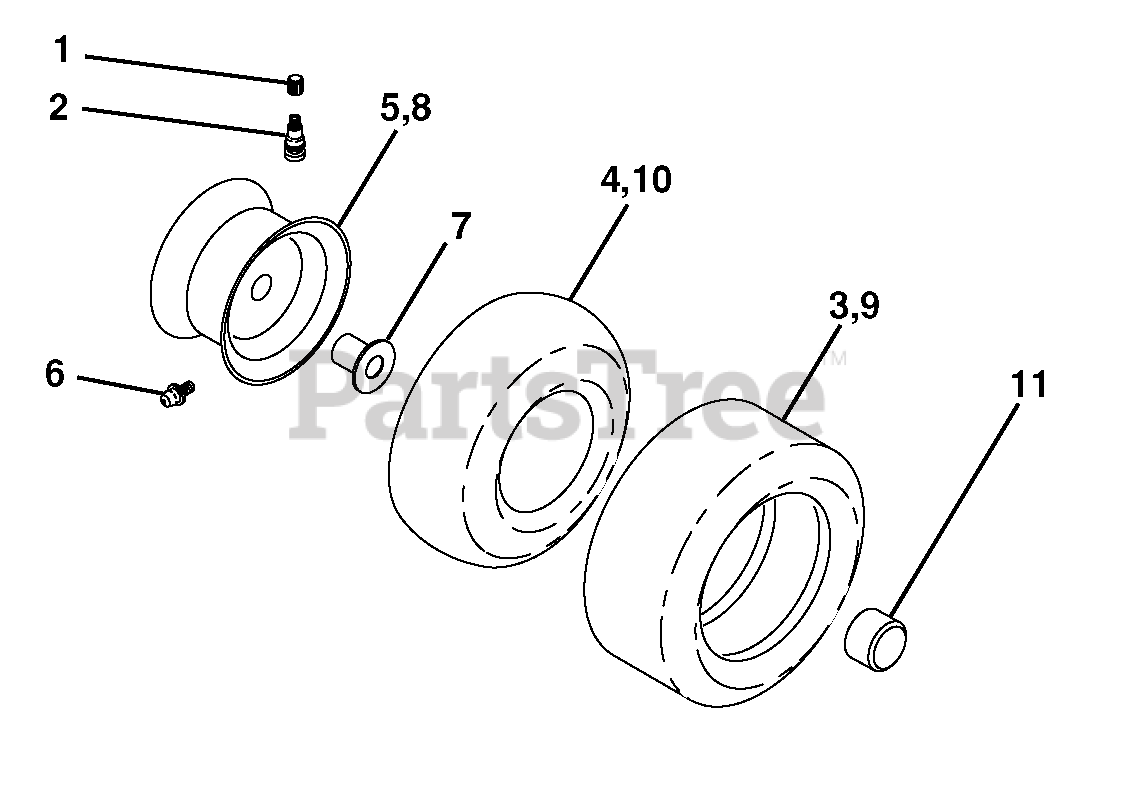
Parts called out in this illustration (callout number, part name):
1	Cap Valve Tire
2	Stem Valve
3	Tire F T 15 x 6 0 - 6
4	Tube Front
5	Rim Asm 6" Front
6	Fitting Grease
7	Bearing Flange
8	Rim Asm 8" rear
9	Tire R T 18 x 9.5-8 Turf Saver
9	Tire R T 18 x 9.5-8 Turf Saver LT
10	Tube Rear
11	Cap Axle Blk 1 50 x 1 00
11	Sealant, Tire (10 oz. Tube)
